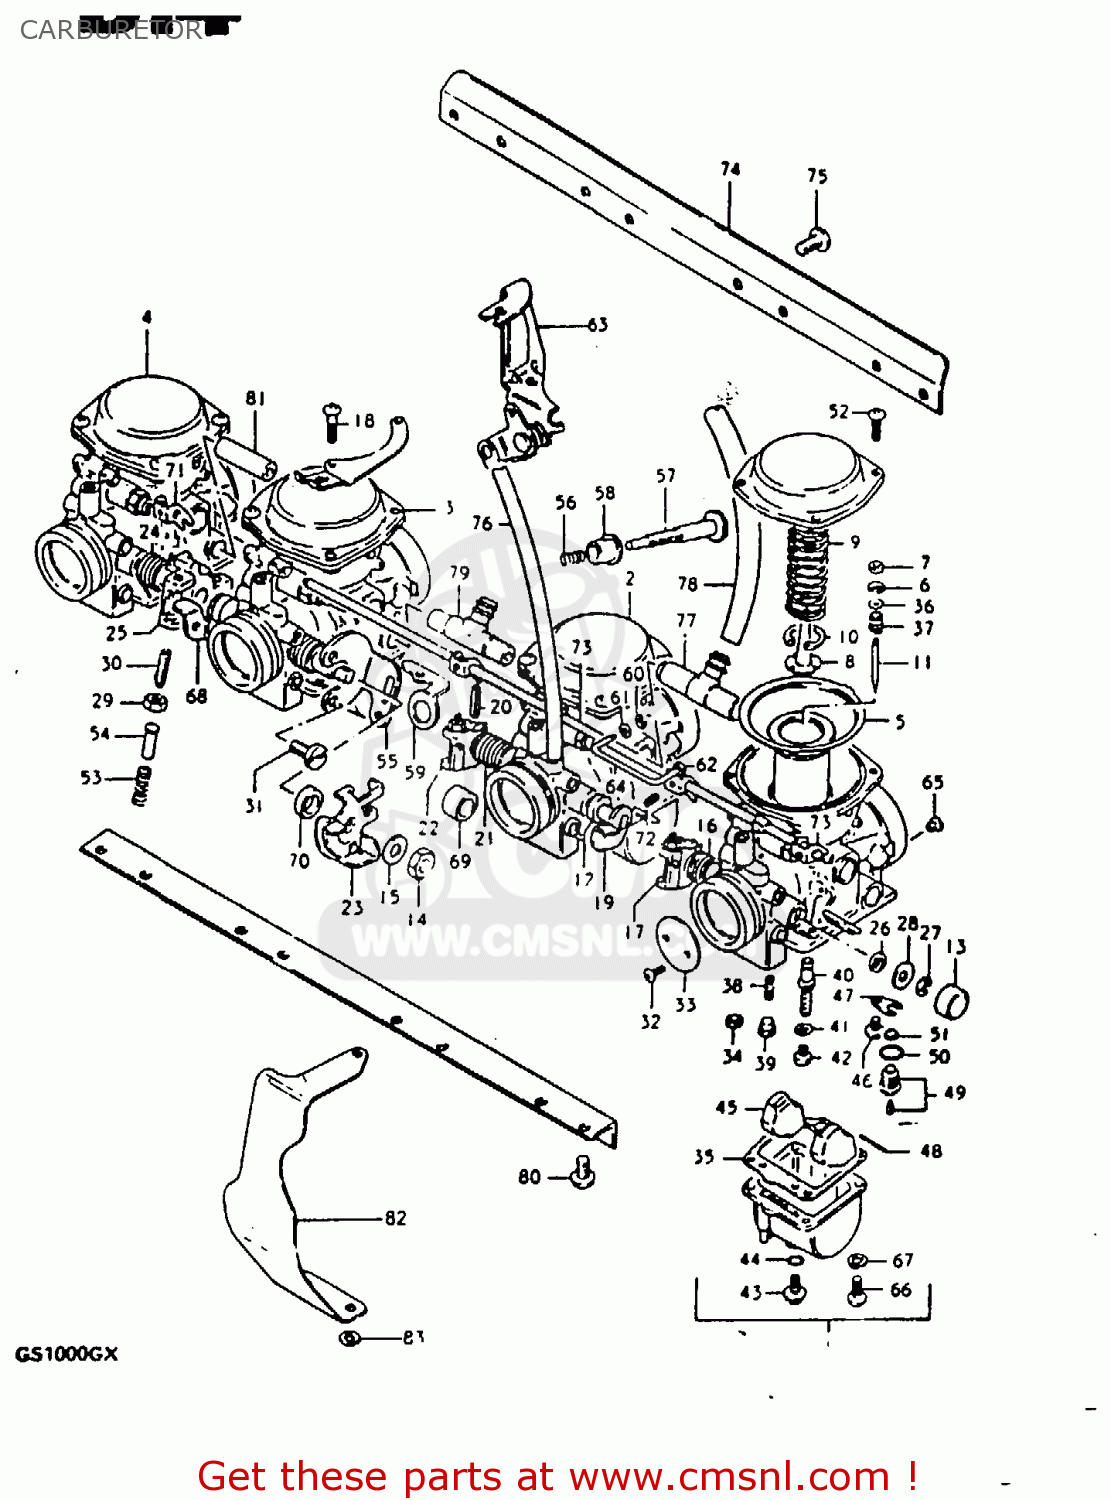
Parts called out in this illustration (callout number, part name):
1	CARBURETOR, NO.1
2	CARBURETOR, NO.2
3	CARBURETOR, NO.3
4	CARBURETOR, NO.4
5	DIAPHRAGM ASSEMBLY
6	CLIP,NEEDLE
7	RING
8	HOLDER,GUIDE
9	SPRING
10	E RING
11	NEEDLE, JET (5057-2)
12	GASKET
13	CAP
14	NUT
15	WASHER
16	SPRING,THROTTLE SHAFT
17	SHAFT,THROTTLE
18	SCREW
19	SHAFT,THROTTLE
20	PIN,THROTTLE SHAFT
21	SPRING,THROTTLE SHAFT
22	LEVER,THROTTLE SHAFT
23	LEVER ASSEMBLY,THROTTLE
24	SPRING,THROTTLE SHAFT
25	SHAFT,THROTTLE
26	SEAL
27	E RING
28	GASKET,THROTTLE SHAFT (NAS)
29	NUT
30	SCREW
31	SCREW
32	SCREW
33	VALVE,THROTTLE
34	GASKET (NAS)
35	GASKET,FLOAT CHAMBER (NAS)
36	WASHER
37	SPRING
38	JET
39	PLUG,NEEDLE JET
40	JET, NEEDLE (X-8)
41	WASHER,NEEDLE NOZZLE
42	JET
43	PLUG,DRAIN
44	GASKET (NAS)
45	FLOAT
46	SCREW
47	PLATE
48	PIN,FLOAT
49	VALVE ASSEMBLY,NEEDLE
50	O RING
51	FILTER
52	SCREW
53	SPRING,THROTTLE SCREW
54	PIN,THROTTLE LEVER
55	BRACKET,THROTTLE ADJUST
56	SPRING
57	SCREW
58	BUSH
59	BRACKET,THROTTLE ADJUST
60	CAP,LEVER
61	SEAT,SPRING
62	LEVER ASSY
63	BRACKET
64	ROD,STARTER LEVER
65	JET
66	SCREW
67	LOCK WASHER
68	SHAFT,THROTTLE
69	RING
70	RING
71	LEVER
72	SCREW
73	SHAFT,STARTER
74	BRACKET
75	SCREW
76	HOSE
77	NIPPLE
78	HOSE
79	NIPPLE
80	SCREW 6X12
81	NIPPLE
82	CLAMP
83	CLAMP
